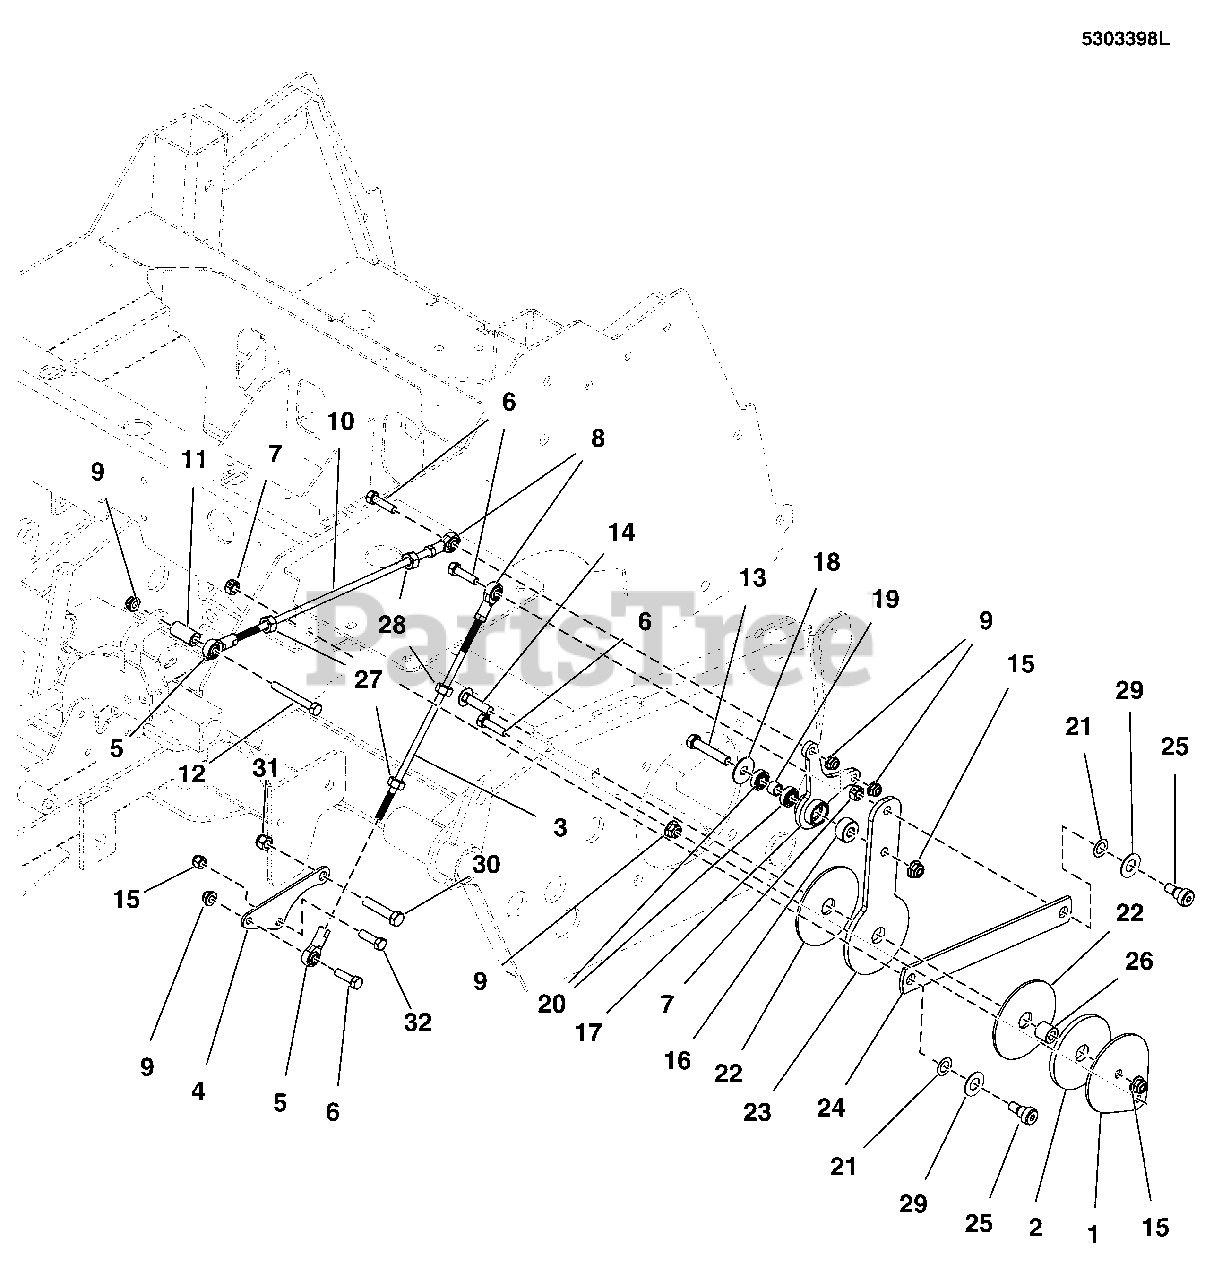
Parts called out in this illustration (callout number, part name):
1	PLATE, CONTROL SYSTEM LOCK - BLK
2	PAD, .77 X 3.50 X .25, POLYURETHANE
3	ROD, HYDRO LINKAGE
4	PLATE, CONTROL MOUNT - BLK
5	BALL JOINT, 5/16-24, RH FEMALE BRONZE RACE
6	CAPSCREW, Hex Head, 5/16-18 X 1-1/4
7	NUT, Hex, Side Lock, 3/8-16
8	BALL JOINT 5/16-24 LH FEMALE BRONZE RACE
9	NUT, Ny Lock Flange, 5/16-18
10	ROD, HYDRO LINKAGE, 14.63
11	SPACER, .33 X .63 X 1.25, CZ
12	CAPSCREW, Hex Head, 5/16-18 x 2-1/2
13	BOLT, 3/8-16 X 2-1/2"
14	BOLT, Carriage, 3/8-16 X 1 1/2, GR5
15	NUT, 3/8-16, Hex Flange Nylock
16	SPACER, .39 X 1.00 X .50, PM, CZ
17	PIVOT, CONTROL SYSTEM
18	WASHER, Fender, 3/8
19	SPACER, .39 X .55 X .38, CZ
20	BEARING, .375" ID X .875" OD X .341" THK
21	WAVE WASHER, 1/2"ID X 087"OD X .01 THK.
22	PAD, CONTROL SYSTEM
23	PLATE, CONTROL SYSTEM ARM - HT
24	LINK, CONTROL SYSTEM ARM, IS2100 - BLK
25	BOLT, 3/8-16 X 3/8", 1/2" SHOULDER
26	SPACER, .39 X .75 X .69, CZ
27	NUT, Hex, 5/16-24
28	NUT, Hex, 5/16-24, LH
29	WASHER, 1/2" GR. 9 FLAT
30	BOLT, 7/16-14 X 1 GD5
31	NUT, 7/16-14 HEX NYLON LOCK
32	CAPSCREW, Hex Head, 3/8-16 x 1
